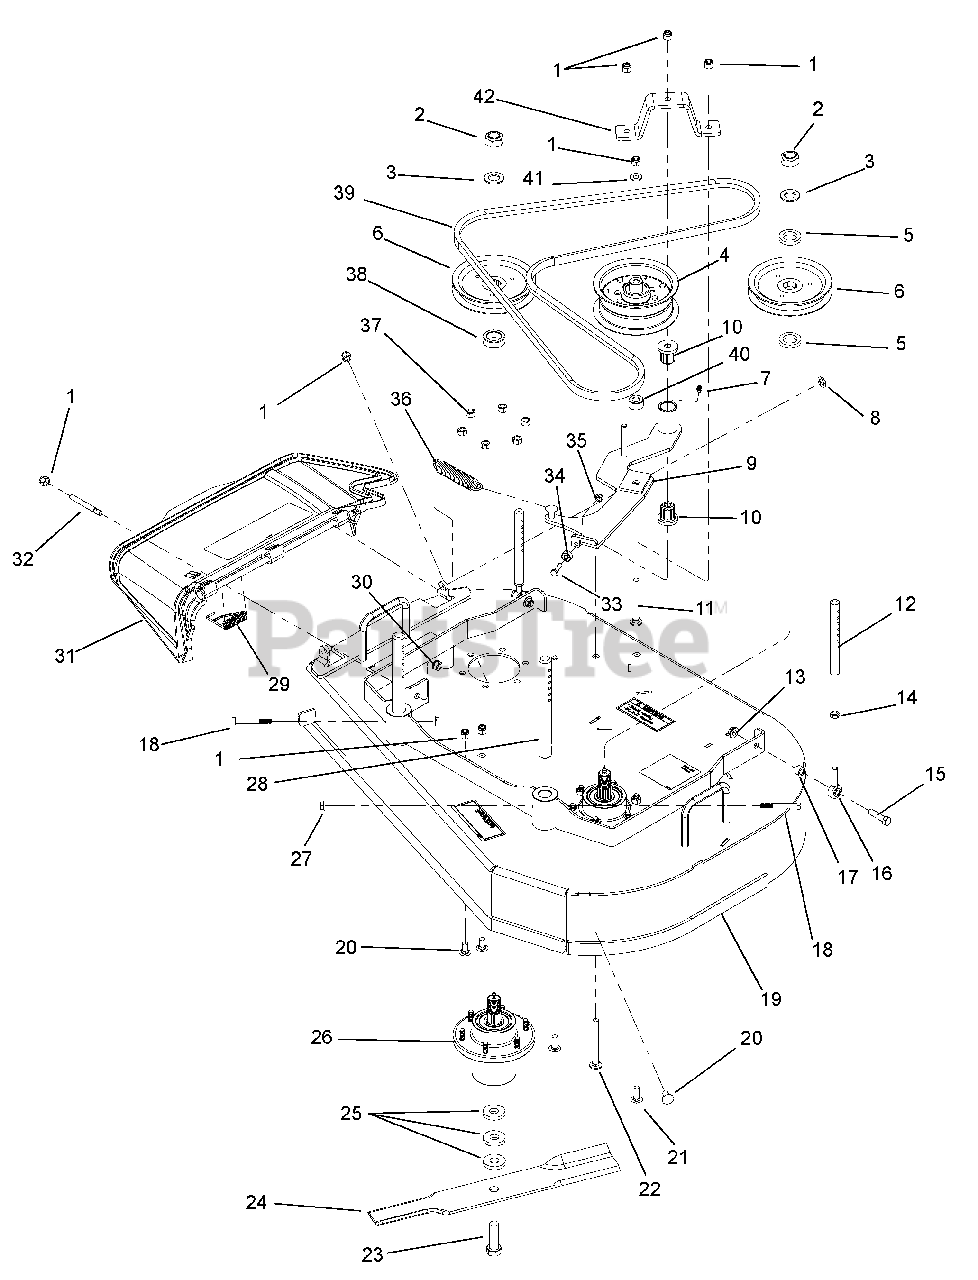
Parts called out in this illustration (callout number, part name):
1	LOCKNUT, 3/8-16 NYLOC Y
2	LOCKNUT, 3/4-16 CROWN C
3	WASHER, .75 X 1.3125 X .113
4	PULLEY, FLAT 5.00 X 2.36 X .375
5	WSHR, FL-STL 1.0 X 1.5 X .25
6	PULLEY, SPLINE SPINDLE SHFLWLK
7	FTG, 1/4-28 STRGT GREASE ZERK
8	RETAINER #
9	WLDT, IDLER ARM 36
10	BRG, FLG M10 X M25 X M27 FLUTED
11	BOLT, 3/8-16 X 3.50 CRG 5 Y
12	ROD, REAR HOC
13	NUT, LK TOP FLG .375-16 YWZC REV
14	NUT, JAM .375-24 YWZC REV
15	BOLT, 3/8-16 X 1.50 HEX 5 Y
16	ROD, END 3/8 RH REV
17	BSHG - SLV REV
18	BOLT, 5/16-18 X 2.50 HEX 8 Y
19	ASSY, 36" FLWLK DECK W/DECALS
20	BOLT, 3/8-16 X 3/4 CRG 5 LN Y
21	BOLT, 3/8-16 X 1.00 CRG 5 SN Y
22	BLT, RDHDSQNK .375-16 X 3.75 YWZC
23	BOLT, 5/8-11 X 2.00 HEX 8 Y
24	BLADE, 18"
25	WASHER, BLADE
26	ASSY, SPINDLE HOUSING
27	LOCKNUT, 5/16-18 WHIZ Y
28	ROD, FRONT HOC
29	SPRING, DISCHARGE CHUTE
30	LOCKNUT, 3/8-16 WHIZ Y
31	CHUTE DISCHARGE ASST #
32	ROD, THREADED ADJUSTMENT
33	BOLT, 1/4-20 X 1.00 HEX 5 Y
34	BRG, BAL .250 X .688 X .313
35	LOCKNUT, 1/4-20 NYLOC Y
36	SPRING, EXT .875 X .125 X 4.25 Y
37	NUT, 3/8-16 STD HEX GR5 Y
38	SPACER, 1.500 X 1.000 X .510 Y
39	BELT, HB 85.1 EL AMD
40	SPACER, .437 X 1.00 X .58 SMLS
41	WASHER, .406 X .813 X .065 FLAT Y
42	STRAP, IDLER 36
